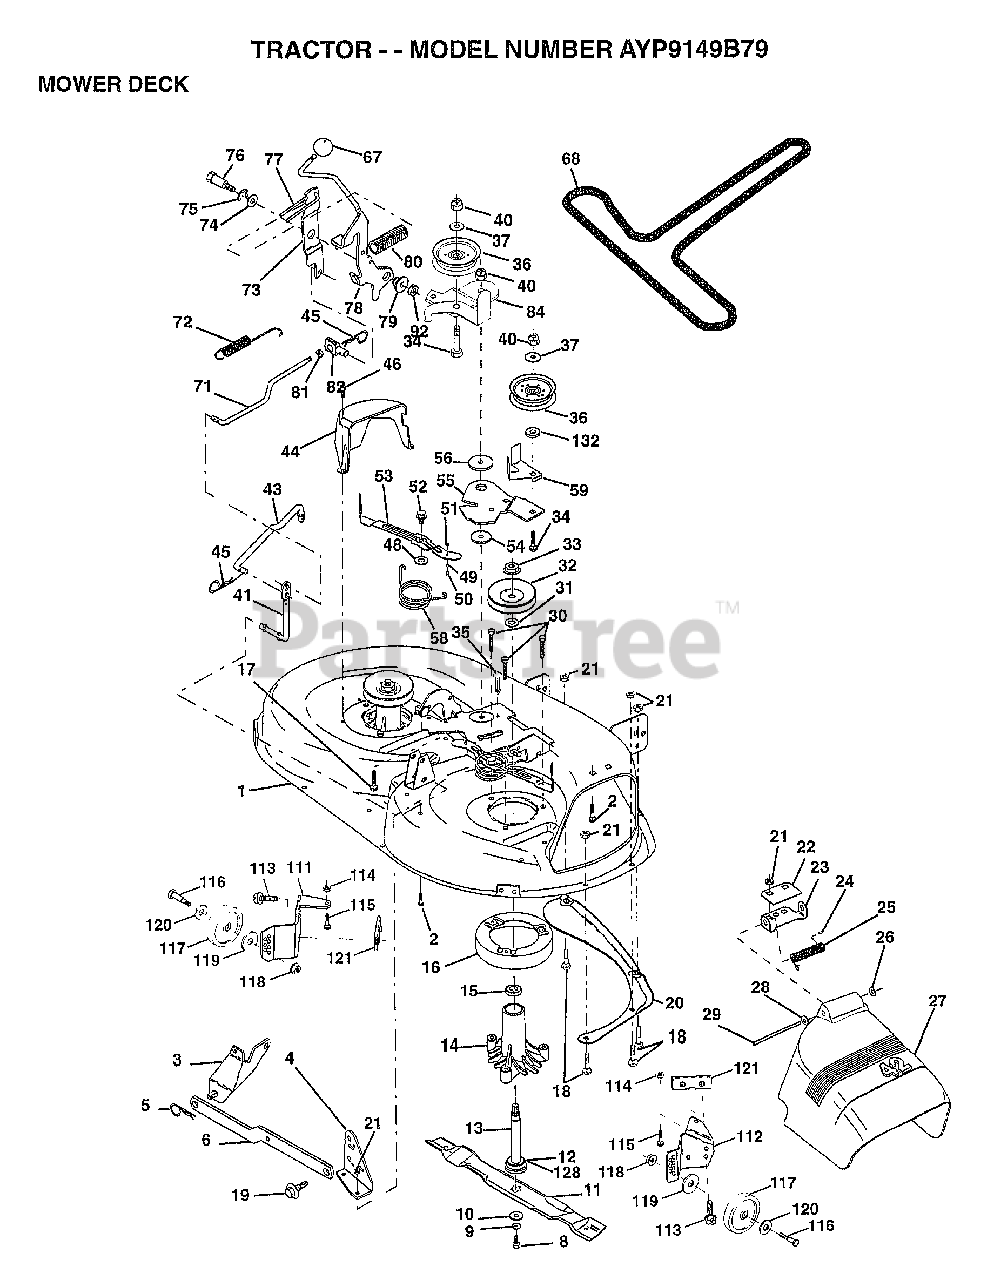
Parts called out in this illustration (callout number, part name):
1	DECK.WELD.42.
2	BOLT
3	BRKT ASM SWAY BAR
4	BRKT DECK SW BAR
8	BLADE BOLT
10	WASHER.HARD.BLADE
11	"BLADE.42"" MULCHER"
12	BEARING.BALL
14	HSG ASM MANDREL
15	BEARING
16	STRIPPER RND MWR
17	BOLT RDHD 3/8-16
18	BOLT
19	BOLT SHD 5/16-18
22	STIFFENER BRKT
23	DEFLECTOR BRKT
24	CAP-SLEEVE LT
25	SPRING TORSION
26	NUT PUSH M
27	DEFLECTOR.SHIELD
28	WASHER
29	HINGE ROD
31	WASHER
32	PULLEY.MANDREL.42
34	BOLT
35	XMAS TREE FASTNER
36	FLAT IDLER PULLEY
37	WASHER
41	PIVOT ROD
43	ROD CLUTCH W/NIBS
44	GUARD MAND LH BLK
45	RETAINER M
46	SCREW.1/4-20X5/8
48	HARD SMALL WASHER
49	ROLLER ASM-CAM
50	SHOULDER BOLT
51	LOCKNUT
52	BOLT.SHLD.5/16-18
54	HARDENED WASHER
55	ARM-IDLER
56	SPACER RETAINER
58	SPRING TORSN BRAK
59	GUARD IDLER TUV
67	KNOB T(3/8 HOLE)
68	BELT-V.SEC.46.KEL
71	ROD CLUTCH 38/42
72	RETURN SPRING
73	CLUTCH ARM SECOND
74	WASHER
75	RING
76	SHOULDER BOLT
77	SPRING KEEPER
78	LEVER ASM-CLUTCH
79	BUSHING
80	SPRING.CLUTCH.MWR
81	NUT
82	TRUNION ADJ
84	BRACKET ASM IDLER
92	NUT
111	BRACKET GUAGE WHEEL LH 42" DECK
112	BRACKET.GWHL.RH.
113	SCREW
116	BOLT M
117	WHEEL.GAGE.BLK.PL
118	LOCKNUT
119	WASHER
120	WASHER
121	BRACKET.EXTRD.GWL
128	WASHER.FELT.
132	WASHER GT
